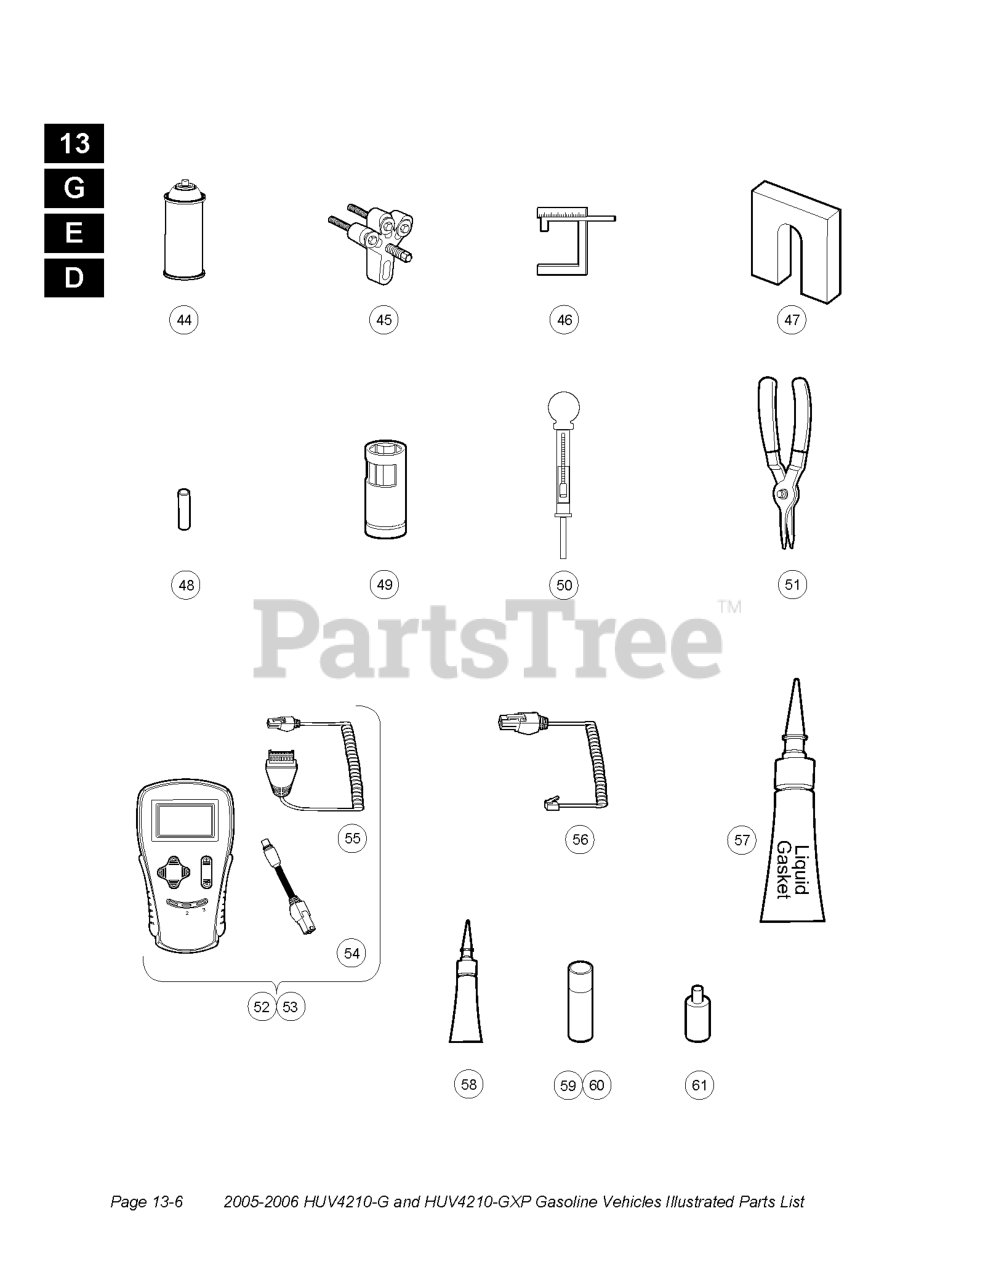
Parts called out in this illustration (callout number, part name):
44	LUBRICANT 11OZ CAN SPRAY
45	FLYWHEEL PULLER KIT
46	GAUGE, CARB FLOAT LEVEL
48	INSERT TOOL, GOVERNOR SHAFT
50	HYDROMETER
51	INERNAL RETAINING RING PLIERS
57	SEALANT
59	TOUCH UP PAINT, BLACK
59	TOUCH UP PAINT BEIGE
59	TOUCH UP PAINT, DARK GREEN
59	TOUCH UP PAINT, BURGUNDY
59	TOUCH UP PAINT, ROYAL BLUE
59	TOUCH UP PAINT, GRAY
59	TOUCH UP PAINT, WHITE
59	TOUCH UP PAINT, RED
59	TOUCH UP PAINT, CLASSIC BLUE
59	TOUCH UP PAINT, DARK GRAY
60	PAINT, GRAY - SPRAY
61	PAINT PEN, UNDERBODY, BLACK
